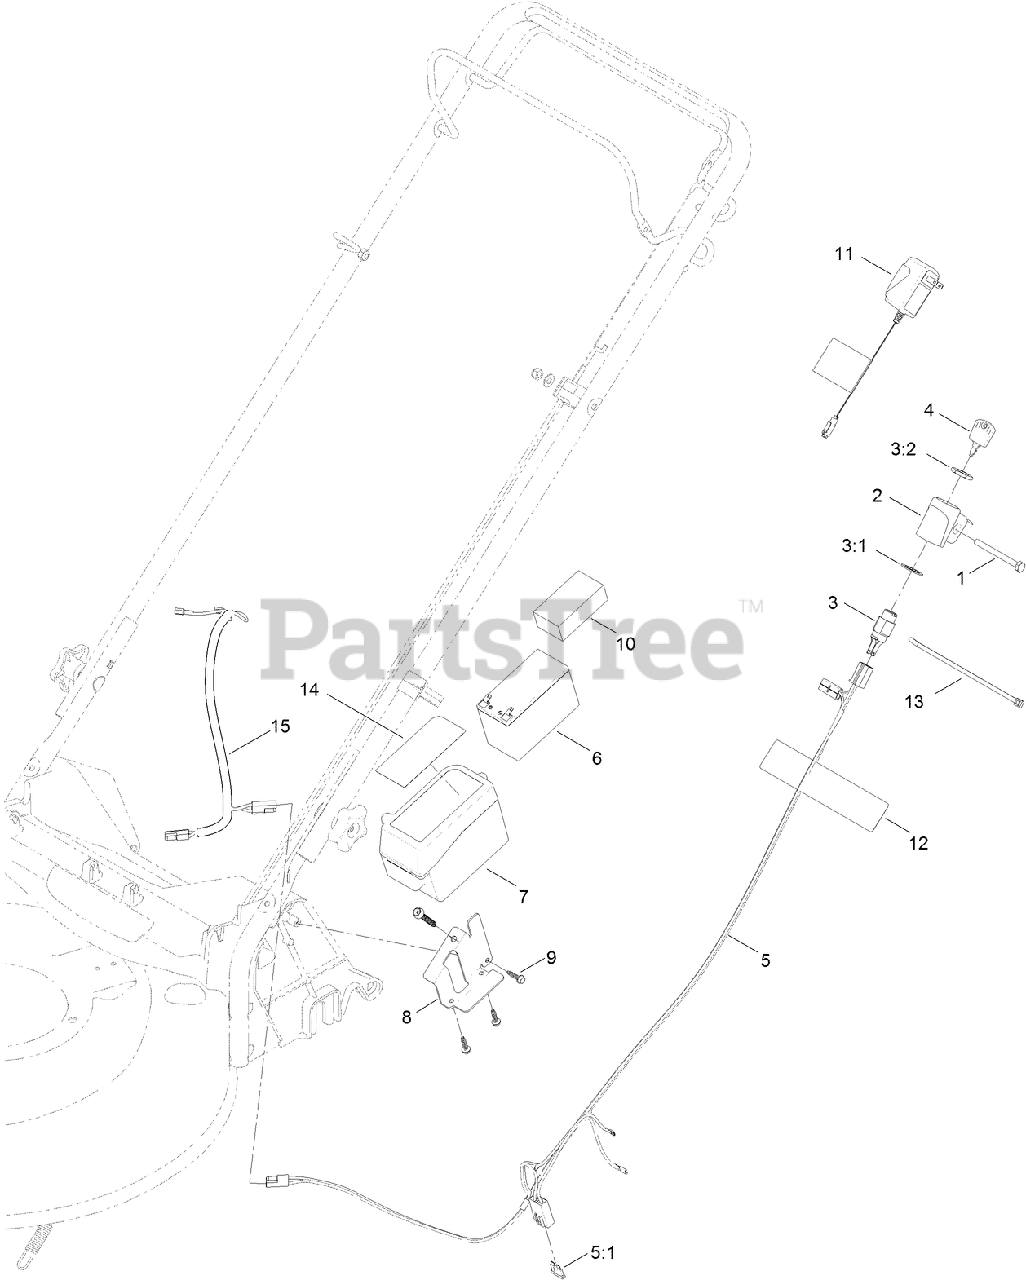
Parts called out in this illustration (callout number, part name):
1	SCREW-HH
2	MOUNT-SWITCH
3	STARTER SWITCH ASM
3:1	WASHER-LOCK
5	HARNESS-WIRE
5:1	FUSE-40 AMP
6	BATTERY-NONSPILLABLE, 12 V
7	BATTERY BOX ASM
8	BRACKET-BATTERY
9	SCREW-HWH
10	FOAM-BATTERY, TOP
12	DECAL-WARNING
13	TIE-CABLE
15	HARNESS-WIRE
